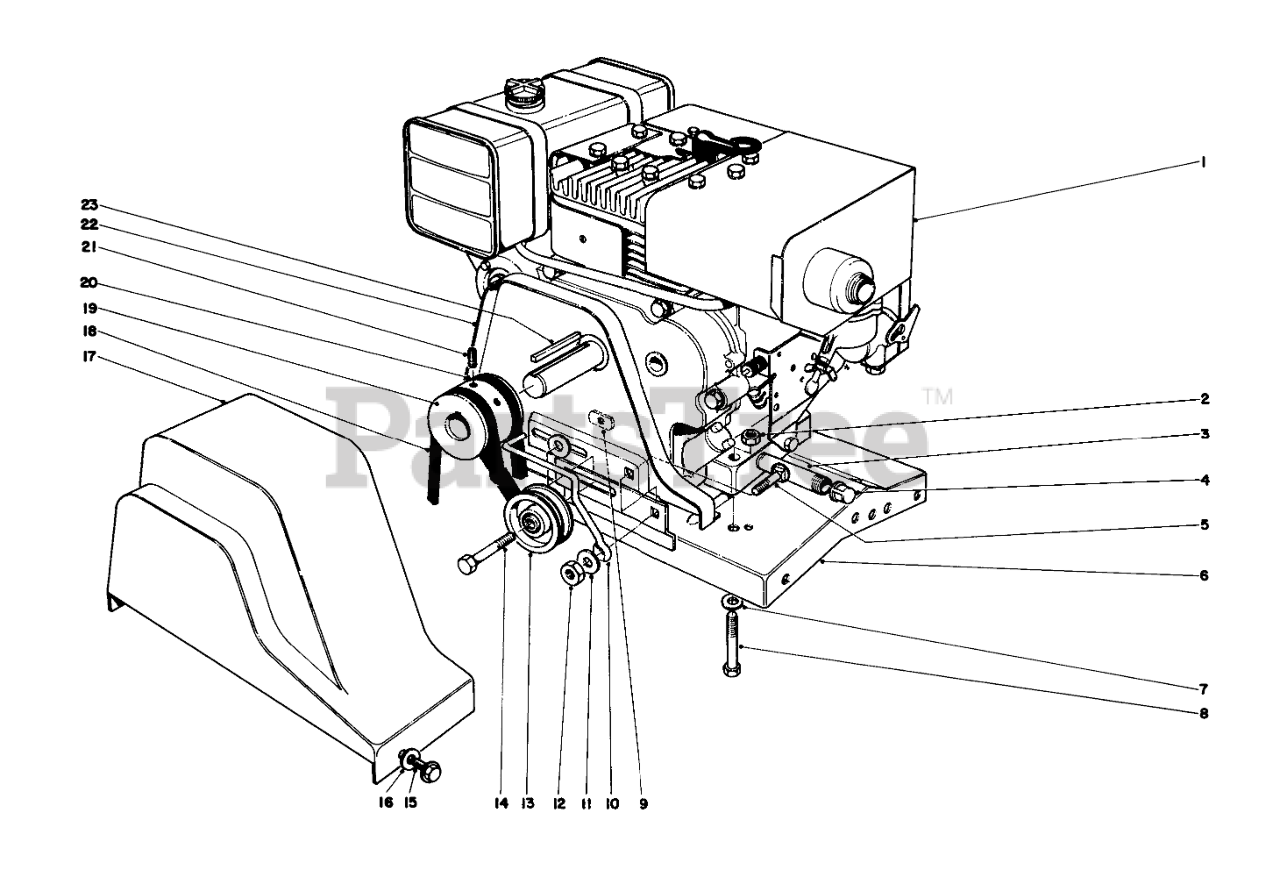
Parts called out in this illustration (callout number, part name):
1	Engine (5 HP)
2	Nut
3	NIPPLE-PIPE
4	CAP-PIPE
5	SCREW-CARR
6	Engine Base
7	WASHER-FLAT
8	SCREW-HH
9	Weldnut
10	BELT GUIDE
11	WASHER-FLAT
12	NUT-HEX
13	PULLEY-IDLER
14	SCREW-HH
15	Screw, Self-tapping
16	WASHER-FLAT
17	Belt Guard
18	V-Belt
19	Pulley
20	V-Belt
21	Screw-Set
22	Belt Guard
